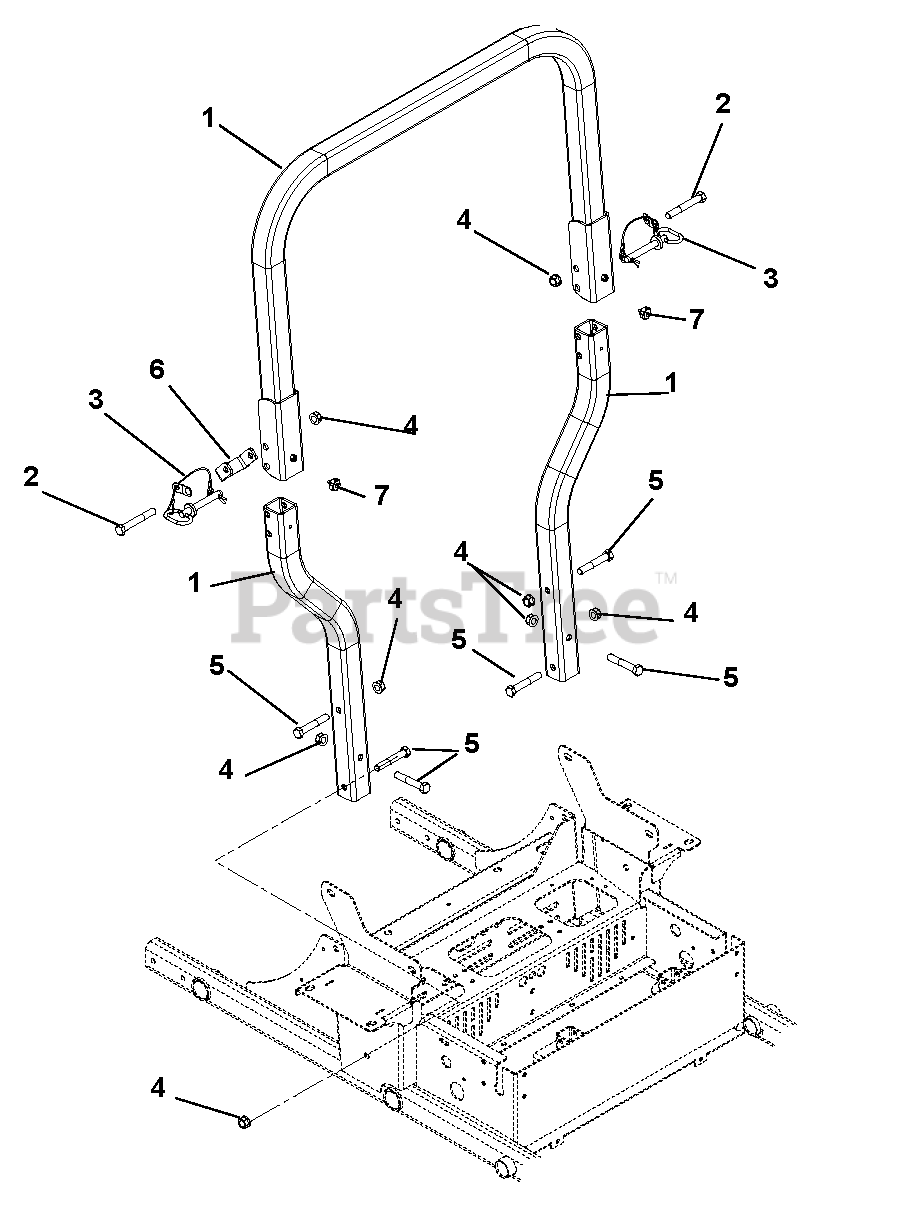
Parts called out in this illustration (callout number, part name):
1	ROPS, PT200 Replacement
2	Bolt, Hex .50-13 x 3.50 Grade 5
3	Assembly, ROPS Pin/Lanyard
4	Nut, Locking Top Flange .50-13
5	Bolt, Hex .50-13 x 3.00 Grade 5
6	Bracket, ROPS Stop, Pro-Turn
7	Knob, Round .312-18 x .750
